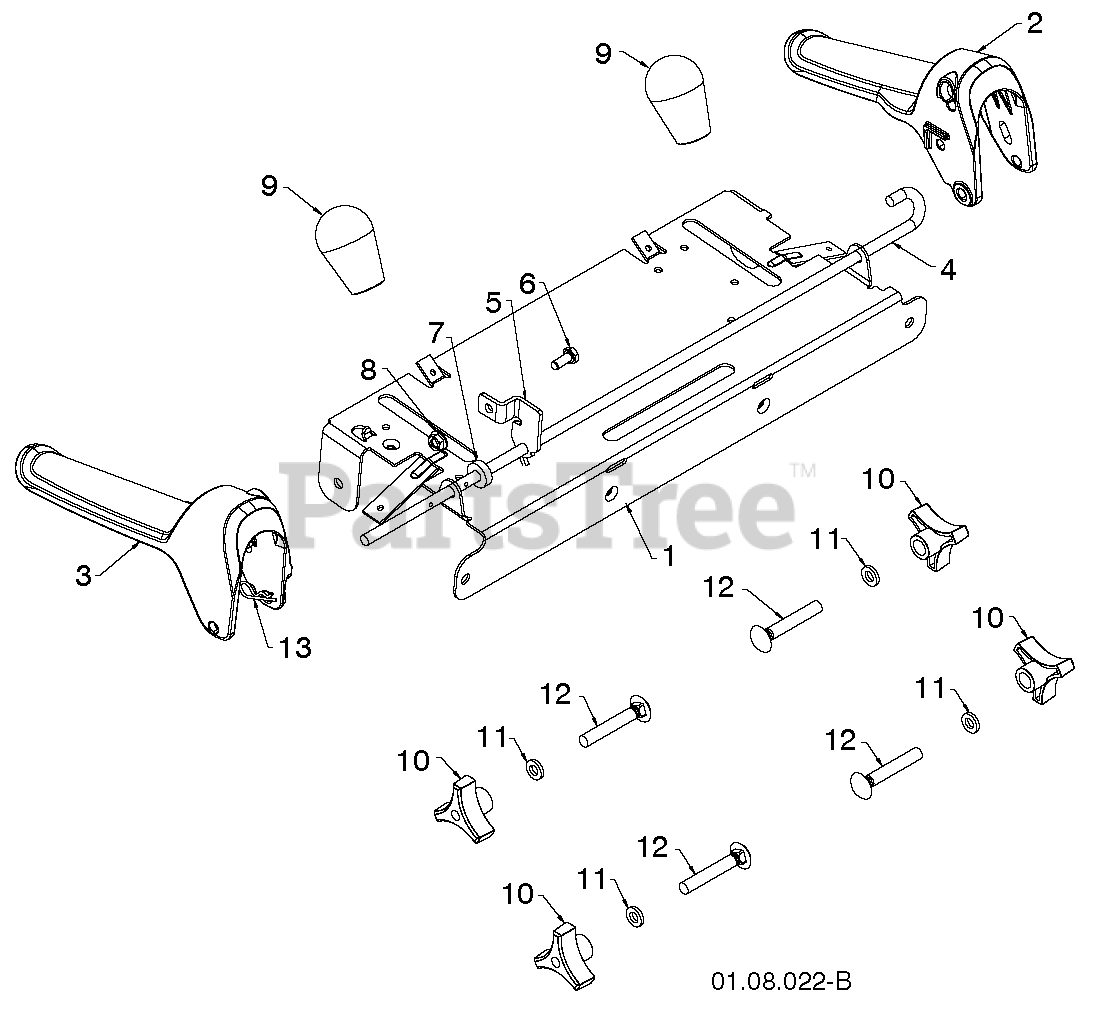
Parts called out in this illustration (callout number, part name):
1	PANEL.CONTROL.SNOW.BLACK
2	LEVER.CONTROL.LH.PL.BLACK
3	LEVER.CONTROL.RH.PL.BLACK
4	BAIL.CONTROL.INTERLOCK.SNOW
5	BRACKET.ARM.IMPELLER.ROD.YZ
6	SCREW 14-20 X 5/8
7	SPACER.CONTROL.LEVER
9	KNOB.OVERMOLD.DS.HUSQVARNA/BLK
10	KNOB.HANDLE.3/8.TRI-POINT.BLAC
11	WASHER
12	BOLT 3/8-16 X 2-1/4
13	SPRING RETAINER
